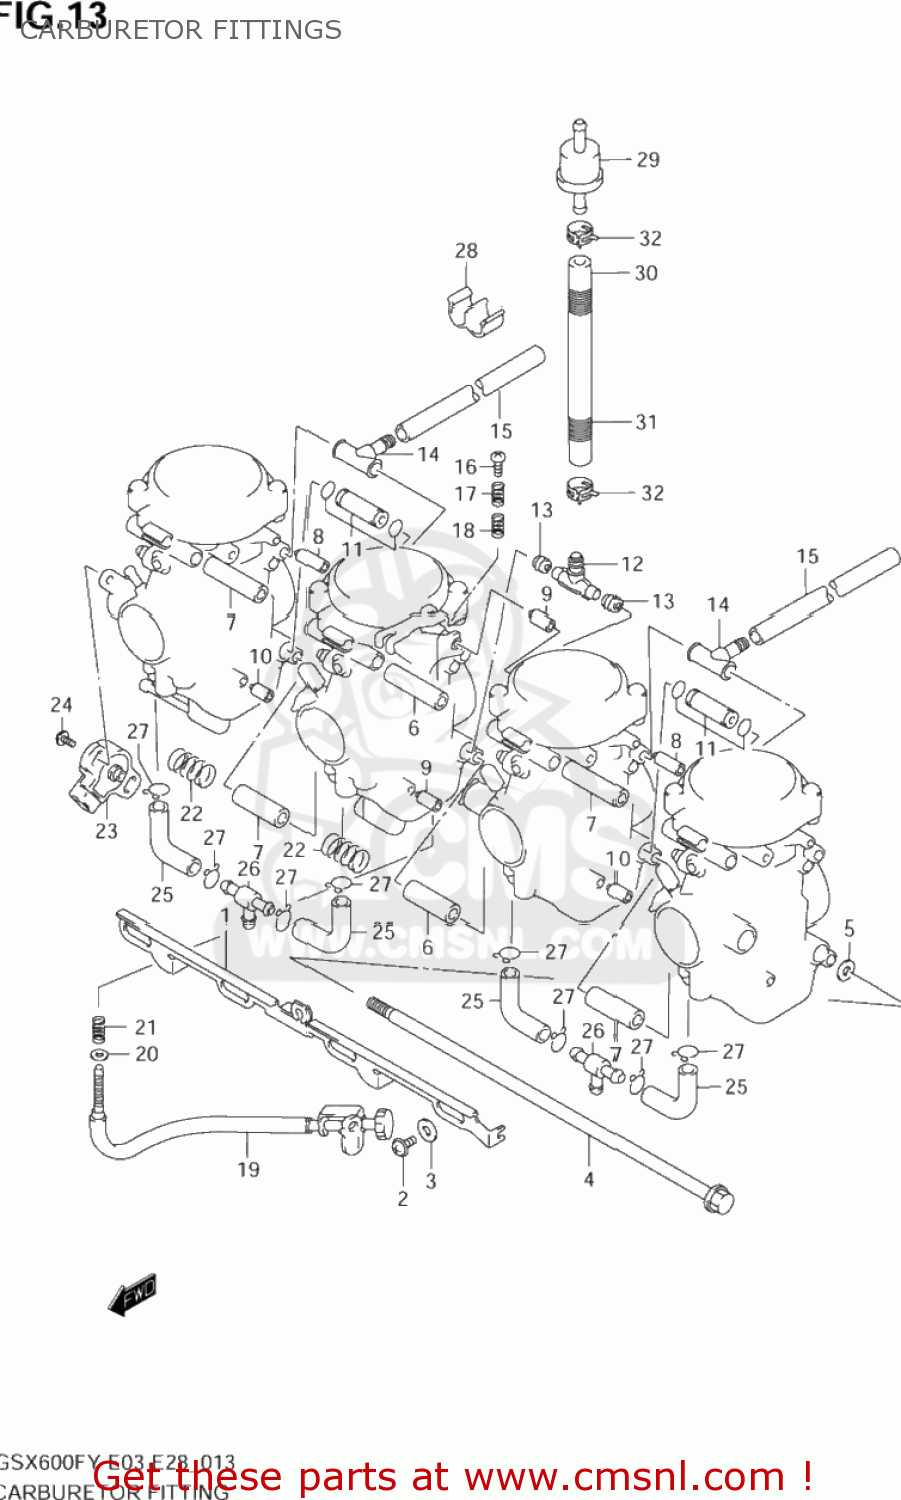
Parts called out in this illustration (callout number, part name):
1	LEVER
2	SCREW
3	PACKING
4	BOLT
5	WASHER
6	PIPE
7	PIPE
8	ROD
9	ROD
10	ROD
11	NIPPLE,CARBURETOR
12	NIPPLE
13	SEAL
14	HOSE
15	HOSE
16	SCREW
17	SPRING
18	SPRING,THROTTLE SCREW
19	SCREW,ADJUST
20	WASHER,STARTER SHAFT
21	SPRING
22	CLIP
23	SENSOR ASSY,THROTTLE
24	SCREW,SENSOR
25	HOSE
26	NIPPLE
27	CLIP
28	CLIP
29	STRAINER COMP,FUEL
30	HOSE(7X12X600)
31	SPRING
